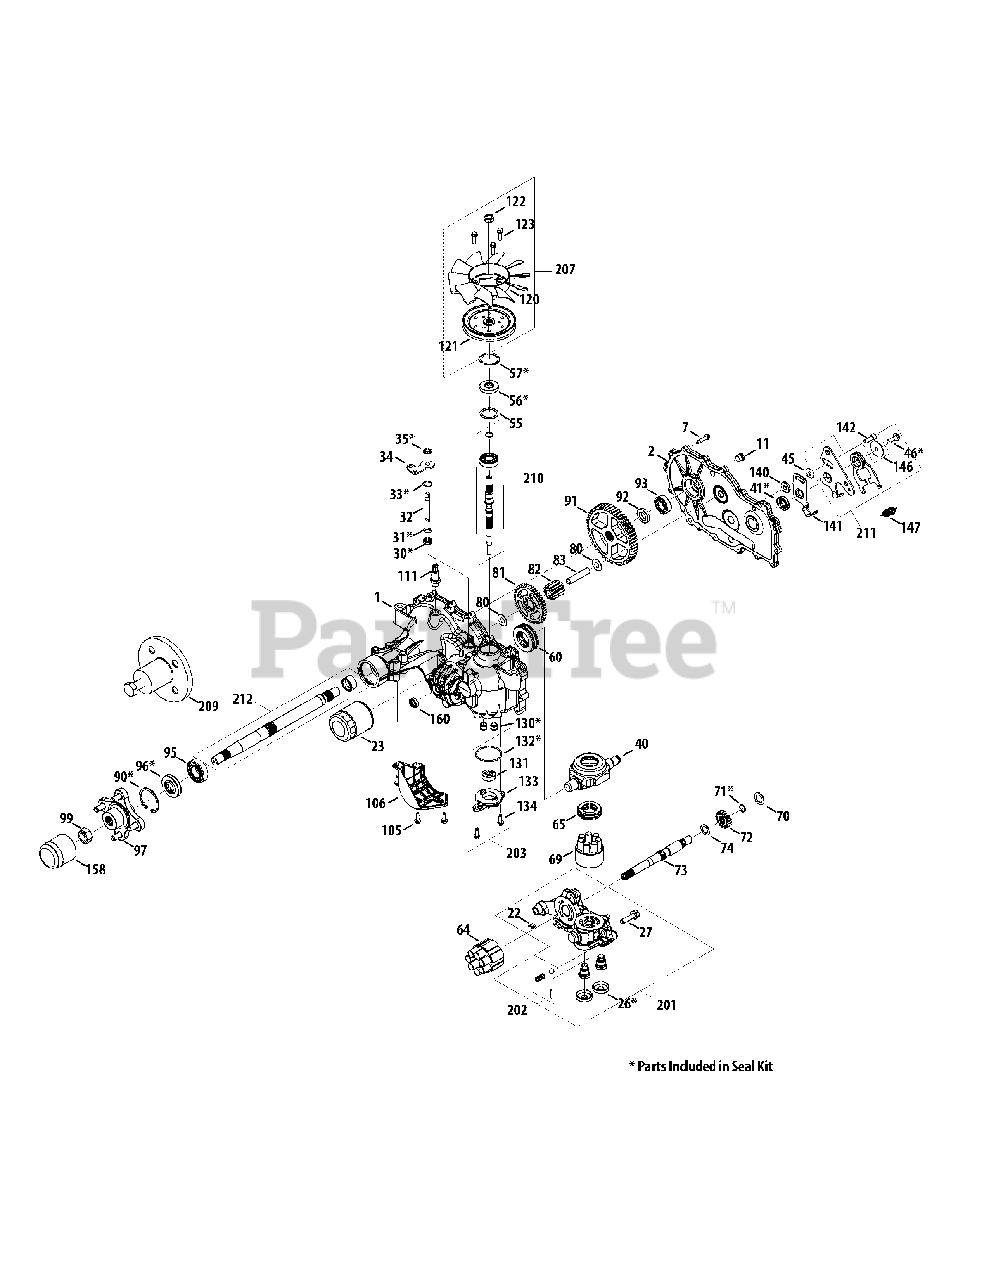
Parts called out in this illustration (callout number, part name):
1	Kit, Housing, Main, RH
2	Kit, Cover, Side, RH
7	Hex Cap Screw, 1/4-20 x 1.125
13	Sealant
22	Plate, Bypass
23	Oil Filter
26	Seal, Plug, 1.25 x .25
27	Hex Cap Screw, 3/8-16 x 1.5
30	Seal, Lip .375 x .75 x .25
31	Ring, Ret .375 External
32	Rod, Bypass
33	Ring, Ret .75 Internal
34	Arm, Bypass
35	Ring, Retaining .375 External
40	Trunnion, Swashplate
41	Seal, Lip 12 x 32 x 7
45	Washer, .34 x .88 x .06
46	Hex Cap Screw, 5/16-24 x 1.00
55	Washer, 1.23 x 1.56 x .04
56	Seal, Lip 17 x 40 x 7
57	Ring, Retaining
60	Bearing, Thrust
64	Cylinder Block Assembly
65	Thrust Ball Bearing, 30 x 52 x 13
69	Block 7 Piston Assembly
70	Washer, .63 x 1.0 x .05
71	Retaining Ring, .625
72	Gear, 14t
73	Motor Shaft
74	Washer, .72 x 1.16 x .04
80	Washer, .5 x 1.0 x .03
81	Gear, 45t
82	Gear, 11t
83	Jack Shaft
90	Retaining Ring, 2.06 Internal
91	Gear, 54t
92	Spacer, .75 x 1.32 x .257
93	Ball Bearing, .75 x 40 x 12
95	Ball Bearing, 1.0 x 52 x 15
96	Seal, Lip 25 x 52 x 10
97	Kit, Hub, 4 Bolt
99	Nut, 3/4-16, Hex Lock
105	Hex Cap Screw, 1/4-20 x .75
106	Guard, Filter, RH
111	Fitting, 9/16-18 SAE .5 Barb
120	Fan 7", 10 Blade
121	Disc, Pulley
122	Nut, 1/2-20, Hex Jam
123	Hex Cap Screw, 1/4-20 x .875
130	Connecting Tube
131	Gerotor Assembly
132	O-Ring, -137, .103 x 2.050
133	Charge Pump Cover
134	Hex Cap Screw, 1/4-20 x .75
140	Spacer, .320 x 1.005 x .179
141	Neutral Left Arm
142	Hex Cap Screw, 5/16-24
146	Washer, .343 x 1.5 x .062
147	Extension Spring, .57 x 2"
160	Seal, Lip, .625 x .875 x .25
201	Kit, Center Section, RH
202	Kit, Charge Relief
203	Kit, Charge Pump
207	Kit, Fan & Pulley
209	Hub Puller, 4 Bolt
210	Kit, Input Shaft
211	Kit, RTN, Bidirectional
212	Kit, Shaft, Axle
